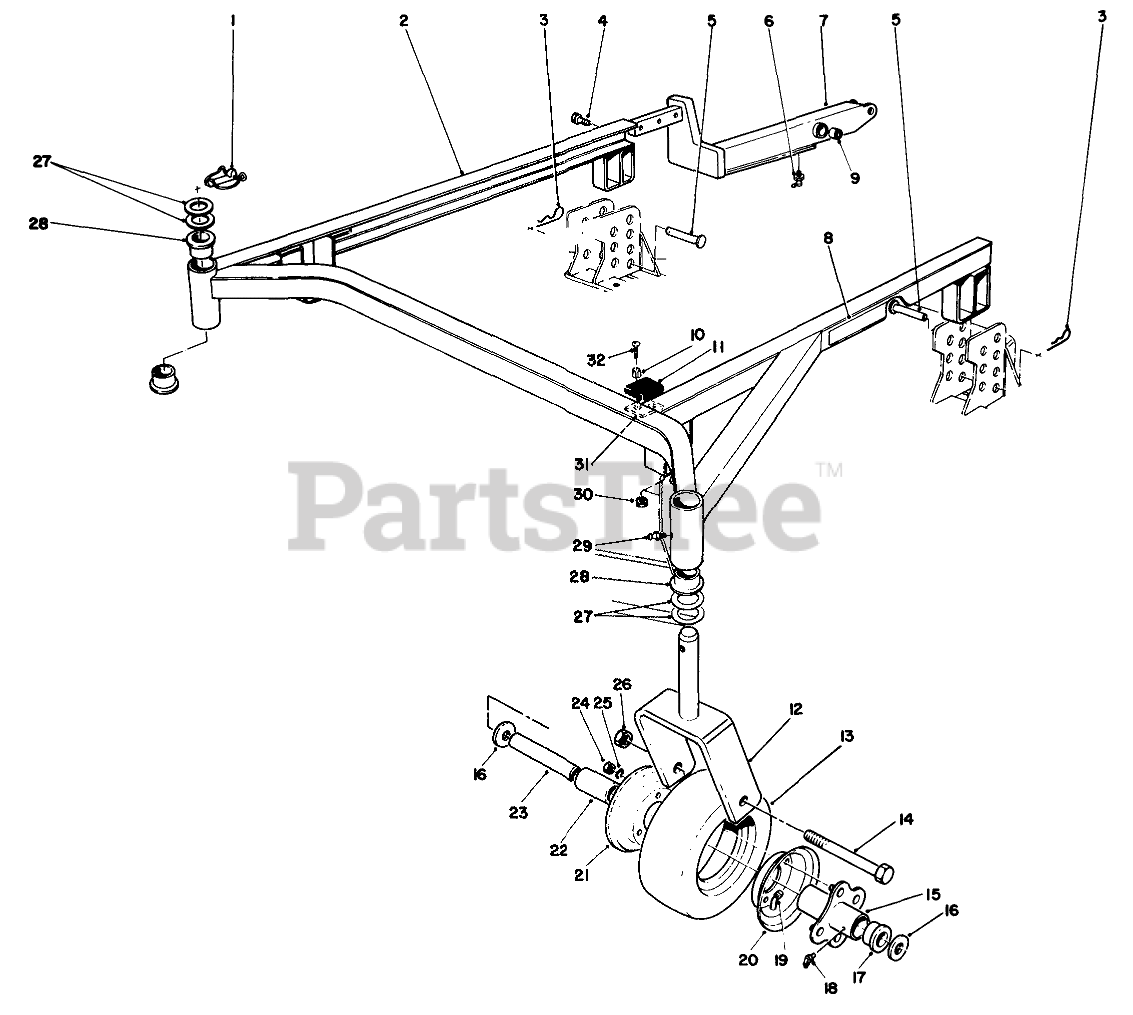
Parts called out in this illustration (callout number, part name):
1	PIN-LYNCH
2	Frame-Deck Suspension (Incl. Ref. #28)
3	PIN-HAIR
4	SCREW-HH
5	PIN-CLEVIS
6	FITTING-GREASE, 90 DEG
7	Lift Arm-R.H.
8	DECAL-HOC, LH
9	7/8 ID X 1.128 X 7/8 LG BSHG
10	SPACER
11	CUSHION-RUBBER
12	Castor Fork
14	SCREW-HH
15	HUB-CENTER
16	WASHER-FLAT
17	BEARING-OUTSIDE
18	FITTING-GREASE
19	TUBE-INNER (W/VALVE)
20	FEMALE WHEEL HALF
21	MALE WHEEL HALF
22	BEARING-ROLLER
23	SPANNER-TIRE
24	NUT-HEX
25	WASHER-LOCK
26	NUT-HEX
27	WASHER-THRUST
28	Bushing
29	FITTING-GREASE
30	NUT-LOCK, NI
31	SHIM-CUSHION
